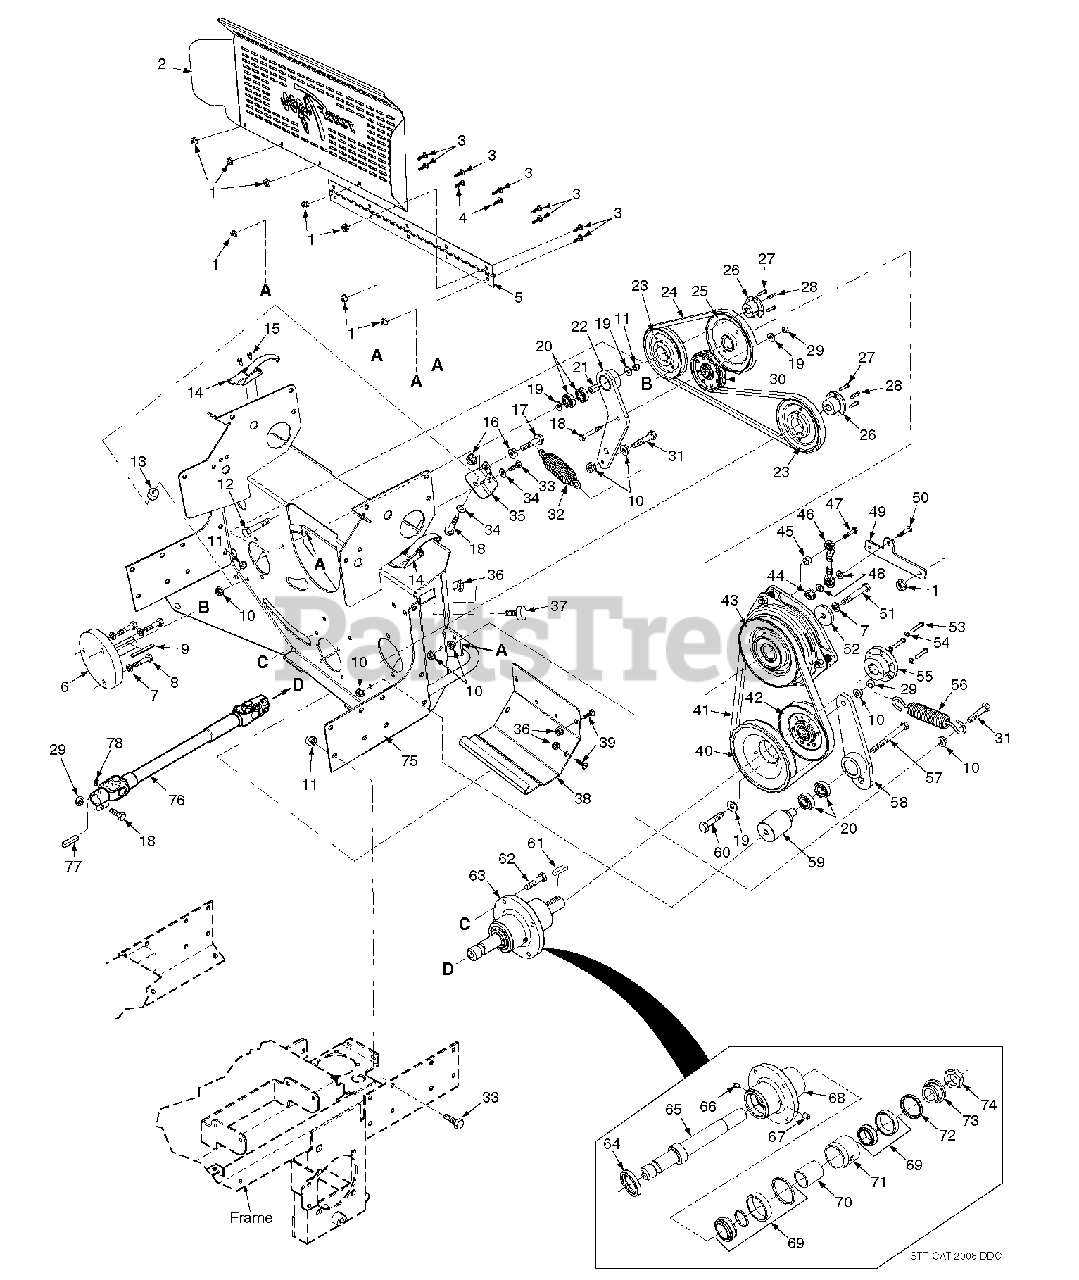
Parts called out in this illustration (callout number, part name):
1	Nut, Serrated Flange 1/4-20
2	Belt Guard, Rear
3	Bolt, Carriage 1/4-20 x 1/2"
4	Bolt, Carriage 1/4-20 x 3/4"
5	Hinge, Belt Guard
6	Stub Shaft
7	Lockwasher, 7/16" Spring
8	Bolt, Hex Head M10 x 1.5 x 35
9	Key, 1/4 x 1/4 x 3-1/4"
10	Nut, Serrated Flange 3/8-16
11	Nut, Elastic Stop 3/8-16
12	Bolt, Hex Head 3/8-16 x 1-3/4" Grd 8
13	Spacer
14	Latch, Hood
15	Screw, #10-32 x .56
16	Nut, Serrated Flange 1/2-13
17	Bolt, Hex Head 1/2-13 x 2" Grd 8
18	Bolt, Hex Head 3/8-16 x 1-3/4"
19	Washer, 3/8" Hardened
20	Ball Bearing
21	Spacer, Idler Bearing
22	Idler Arm Weldment, Pump Drive
23	Pulley, 5.75" O.D. - Kubota
24	Belt, Pump Drive - Kubota
25	Pulley, 5.67" Dia. - 1.125" Bore
26	Tapered Hub, 17mm Bore
27	Bolt, Hex Head 1/4-20 x 1" Grd 8
28	Key, 5 x 5 x 35 mm
29	Nut, Center Lock 3/8-16
30	Pulley, Idler 4" Dia.
31	Bolt, Hex Head 3/8-16 x 1-1/2" Grd 8
32	Spring, Transmission Idler
33	Bolt, Hex Head 3/8-16 x 1"
34	Flatwasher, 3/8-.391 x .938 x .105
35	Bracket
36	Nut, Serrated Flange 5/16-18
37	Bumper, Rubber
38	Cover, Rear
39	Bolt, Carriage 5/16-18 x 3/4"
40	Pulley, 6.35 Tapered Bore
41	Belt, Deck Drive
42	Pulley, Idler 5" Dia.
43	Clutch, Ogura GT 3.5 - 1.125" Bore
44	Nut, Hex Elastic Stop 5/16-18
45	Spacer
46	Rod Assembly, Clutch Anti-Rotation
47	Bolt, Hex Head 5/16-18 x 1-1/2"
48	Flatwasher, 5/16"
49	Bracket, Anchor, Anti-Rotation
50	Bolt, Hex Head 5/16-18 x 1-1/4"
51	Bolt, Hex Head 7/16-20 x 2-1/4"
52	Flatwasher, 7/16-.469 x 1.75 x .25
53	Bolt, Hex Head 1/4-20 x 1-3/8"
54	Lockwasher, 1/4" Spring
55	Tapered Hub, 1" Bore
56	Spring, PTO
57	Bolt, Hex Head 3/8-16 x 4-1/2" Grd 8
58	Idler Arm Weldment, PTO Drive
59	Pivot, Idler PTO
60	Bolt, Hex Head 3/8-16 x 2-1/2" Grd 8
61	Key, 1/4 x 1/4 x 1-1/2"
62	Bolt, Hex Head 5/16-18 x 1-3/4" Grd 8
63	Spindle Assembly, Deck Drive
64	Seal, 2.0 OD x 1.5 Bore
65	Shaft, Deck Drive
66	Grease Fitting, 1/4-28
67	Relief Fitting
68	Spindle Housing
69	Roller Bearing Tapered
70	Spacer, Inside
71	Spacer, Outside
72	Seal, 2.0 OD x 1.625 Bore
73	Spindle Bushing, Bottom
74	Nut, 1.06-18 Thread
75	Pump Mounting Plate Weldment
76	Driveshaft
77	Key, 1/4 x 1/4 x 1"
78	Set Screw, 3/8-16 x 3/4" Torx Socket
